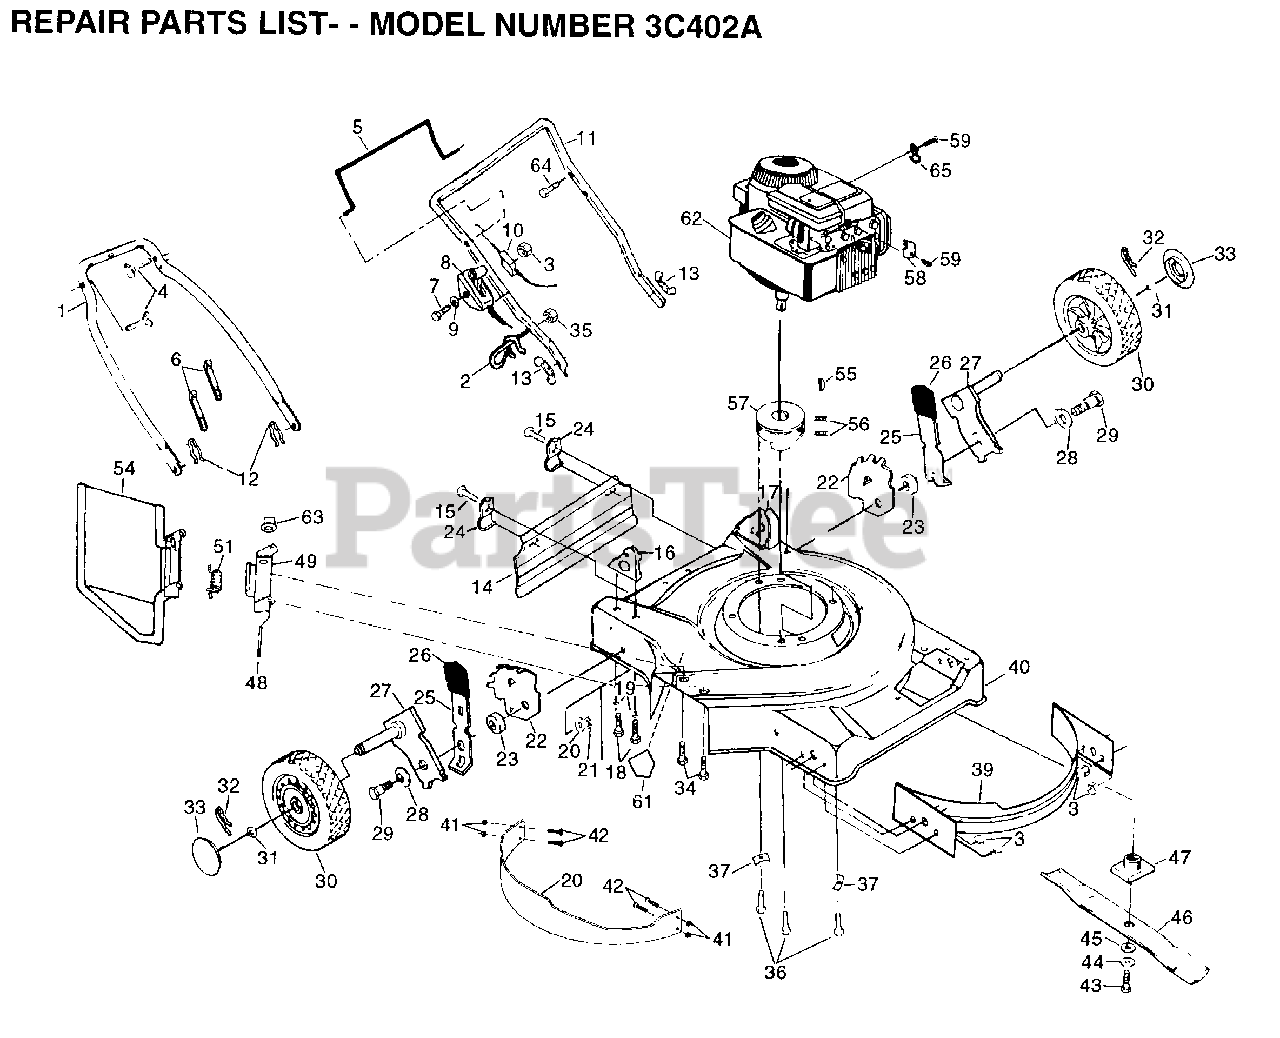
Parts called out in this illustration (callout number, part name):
2	ROPE GUIDE
4	BOLT.HANDLE.LM
5	CONTROL BAR
8	CONTROL THROTTLE
9	WASHER PM
10	"CABLE,ENG ZONE CO"
12	HAIRPIN COTTER
13	"NUT,WING PM"
15	TAPPING SCREW
18	SCREW
19	STEEL WASHER
20	BAFFLE.MULCH.22SD
21	LOCKNUT PM
24	"BRKT,DEFL PM"
25	SPRING SELECTOR
26	KNOB PM
27	AXLE ARM
28	"WASHER, BELLEVIL."
31	WASHER
32	RETAINER CLIP PM
33	HUB CAP
34	SCREW
35	NUT
36	SCREW
39	BAFFLE FRONT 22SD
41	LOCKNUT
43	SCREW
44	LOCKWASHER
45	"WASHER,HARDEN"
47	ADAPTOR.BLADE.LM
48	"ROD,HINGE "
49	"BRKT,HSG"
51	"SPRING,TORSION"
55	HI PRO KEY PM
56	SCREW
57	ENGINE.PULLEY.FWG
58	CABLE CLAMP
59	SCREW PM
61	DECAL-DANGER PM
63	PUSH ON SPEED NUT
64	"SCREW,PAN HD"
65	"CLIP,CABLE"
